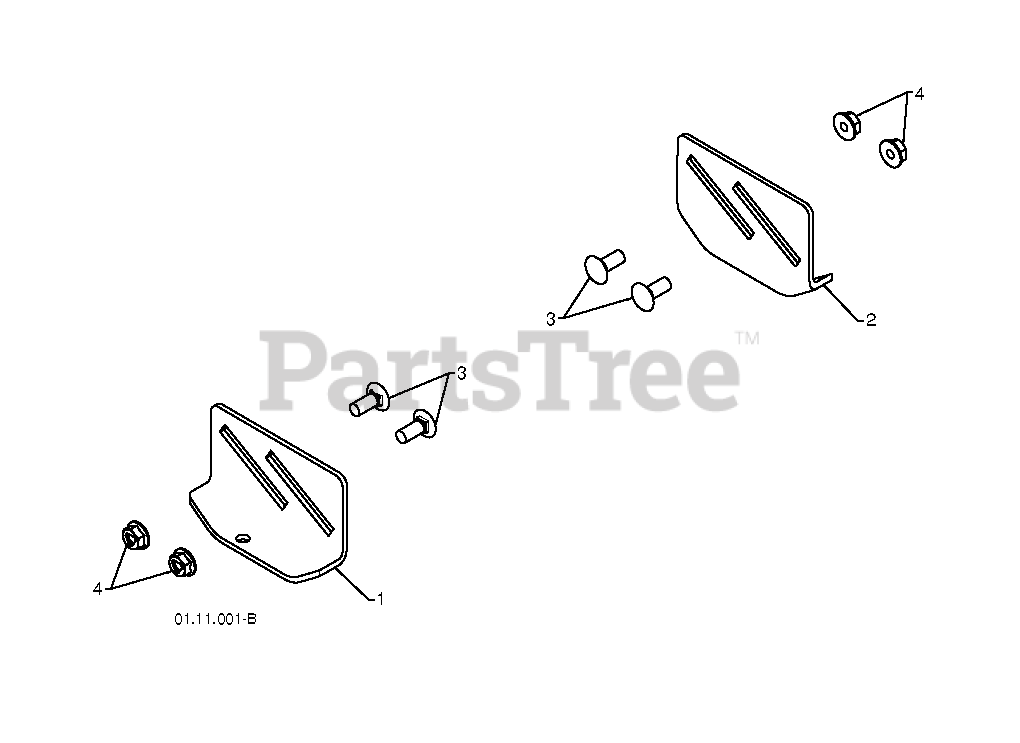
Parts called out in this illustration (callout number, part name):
1	RP PLATE.SKID.LH.PNT
2	PLATE.SKID.ADJ.RH.BLACK
3	BOLT
4	NUT, LOCK 5/16-18
